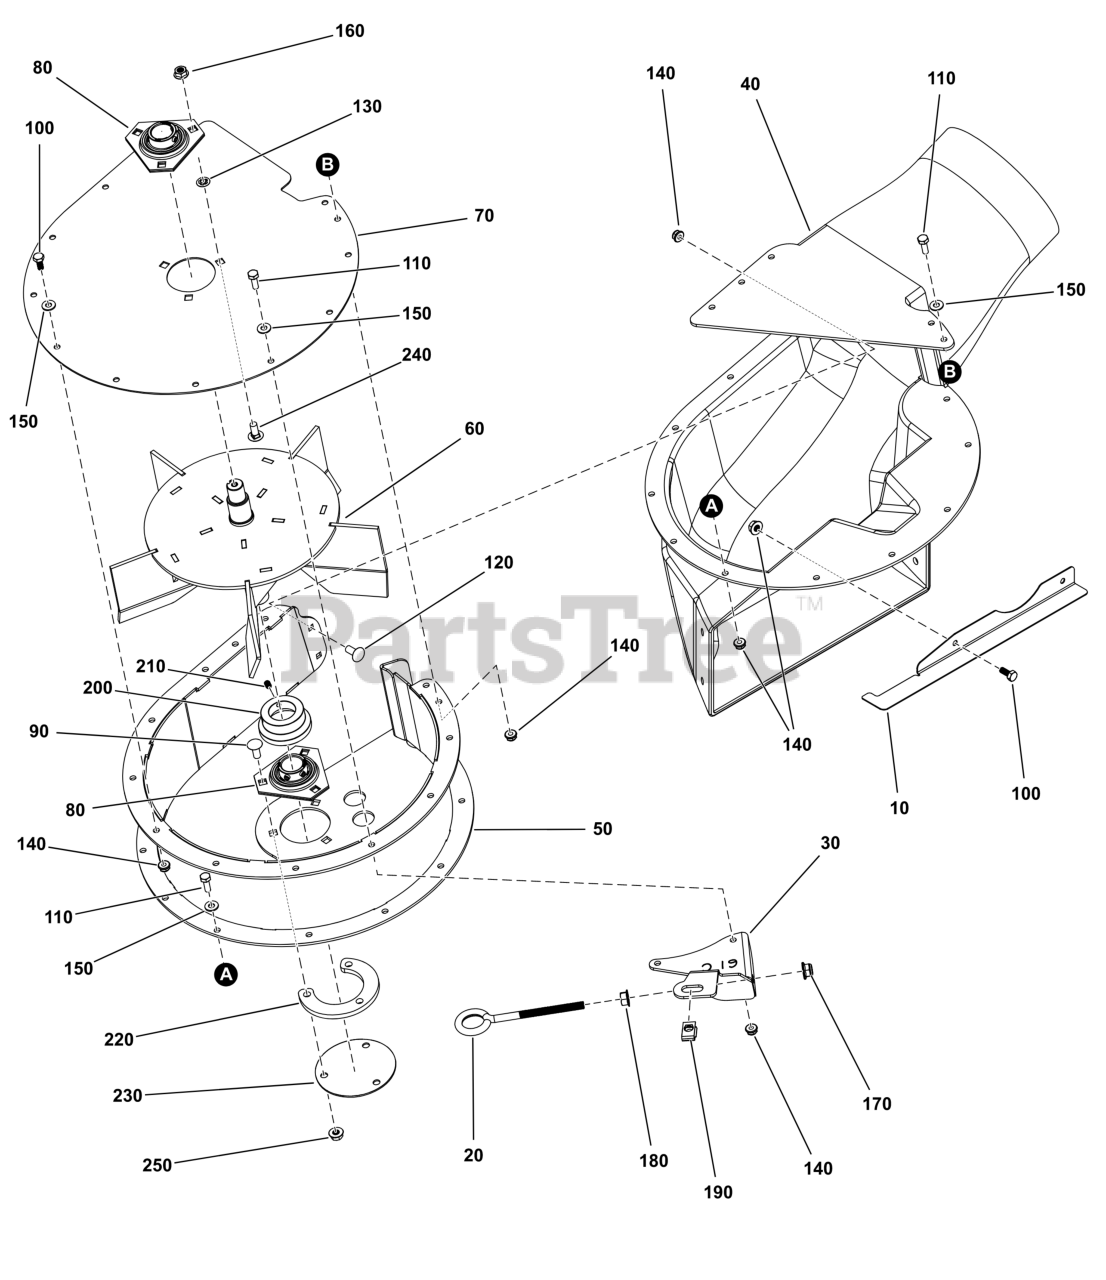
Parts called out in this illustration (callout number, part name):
10	BRACKET, ADAPTER SEAL, COM BLOWER - BLK
20	EYE BOLT, 3/8-16 X 4-
30	WELD, SPRING ANCHOR, COM - BLK
40	HOUSING, BLOWER
50	WELD, FAN CAGE, BLOWER - BLK
70	PLATE, FAN, TOP - BLK
80	BEARING, FLANGE
90	BOLT, 5/16-18 X 1", C
100	BOLT, 1/4-20 X 1", GD
110	BOLT, 1/4-20 X 3/4" G
120	BOLT, 1/4-20X.750, SQ
130	NUT, PUSH ON, 5/16
150	WASHER
160	NUT, 5/16-18 HEX SERR
170	NUT, 3/8-16 HEX NYLOCK
180	NUT, 3/8-16 HEX SERRA
190	BODY CLIP, 5/16-18 X
200	GUARD, BEARING, TMAX
210	SET SCREW, 1/4-20 X 3/8, KNURLED CUP
220	PLATE, C-SHAPED SPACER, TMAX - BLK
230	PLATE, INNER COVER, TMAX - BLK
250	NUT
